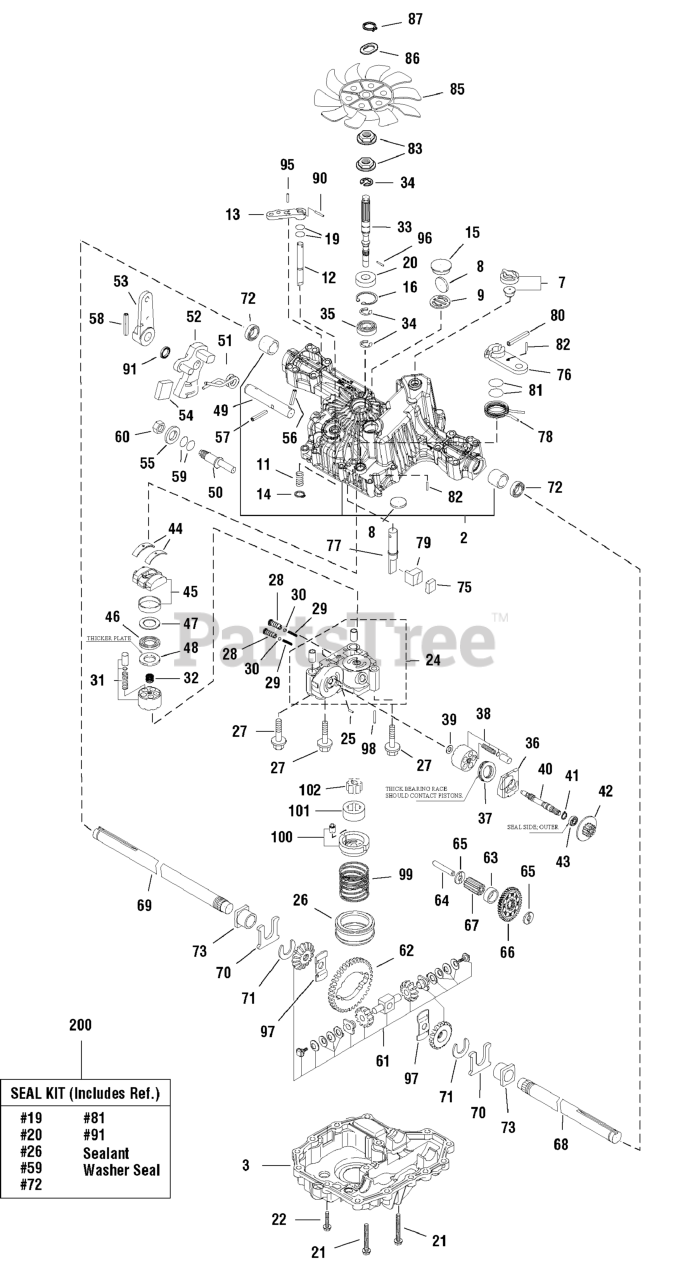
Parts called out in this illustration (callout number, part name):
2	*HOUSING ASSEMBLY, Upper
3	HOUSING, LOWER
7	VENT VALVE 15
9	*HOLDER, Magnet
11	SPRING 25
12	BYPASS SHAFT A
13	LEVER, Bypass
14	RING, Snap, 10
15	SEALING CAP, 30
16	RING, Snap, C 35
19	0-RING, 1A P10A
20	SEAL TC 153507
21	SCREW, Tapping, 8 * 30
22	*SCREW, Tapping
24	CASE, CENTER
25	PIN, 3 * 9.8
27	BOLT, 10 * 75
28	VALVE, IDS 1.0
29	IDS SPRING
31	*CYLINDER BLOCK ASSEMBLY
33	SHAFT, PUMP
34	E-RING, 15
35	BEARING, 6202C3
36	MOTOR HOUSING
37	*BEARING, Thrust
38	KIT, Cylinder Block
39	WASHER, 12 * 24 * 1
40	MOTOR SHAFT
41	RING, Snap, S15
42	BRAKE DISC/MOTOR GEAR (10T)
43	BEARING, 6202UC3
44	THRUST METAL
45	SWASH PLATE ASSEMBLY
46	THRUST PLATE, B
47	THRUST BEARING K81105
48	THRUST PLATE, A
49	*SHAFT, Control
50	*FULCRUM, ECCENTRIC
51	SPRING, Torsion, Standard
52	LEVER, Control
53	CONTROL LEVER C
54	JERKY PLATE
55	WASHER, 12
56	COTTER PIN, 1/8 * 3/4
57	SPRING PIN 6 * 36
58	ROLL PIN 6 * 40
59	O-RING 1A P14
61	GEAR & PINION ASSEMBLY
62	*GEAR, FINAL CONTR TRAC
63	COLLAR, PINION
64	*SHAFT, Reduction
65	WASHER, 12 * 32 * 3.2
66	REDUCTION GEAR (38T)
67	FINAL PINION (10T)
68	AXLE SHAFT, Right
69	AXLE SHAFT, Left
70	THRUST WASHER
71	RING, 17
72	SEAL, 19 * 32 * 8
73	BUSHING, 19 * 25
75	BRAKE SHOE
76	BRAKE LEVER
77	SHAFT, Brake
78	RETURN SPRING B
79	BRAKE ACTUATOR
80	SPRING PIN, 5 * 32
81	O-RING 1A P12
82	SPRING PIN 4 * 16
83	SPLINE COLLAR
85	FAN, White
86	WASHER, Wave
87	RING, Snap
90	SPRING PIN, 3.0A * 20
91	OIL SEAL 16 * 22 * .03
95	SPRING PIN, 3.0A * 20
97	WASHER, THRUST DIFF
99	*SPRING, Charge
100	CHARGE PUMP CASE ASSEMBLY
200	SEAL KIT (K57A & K)
